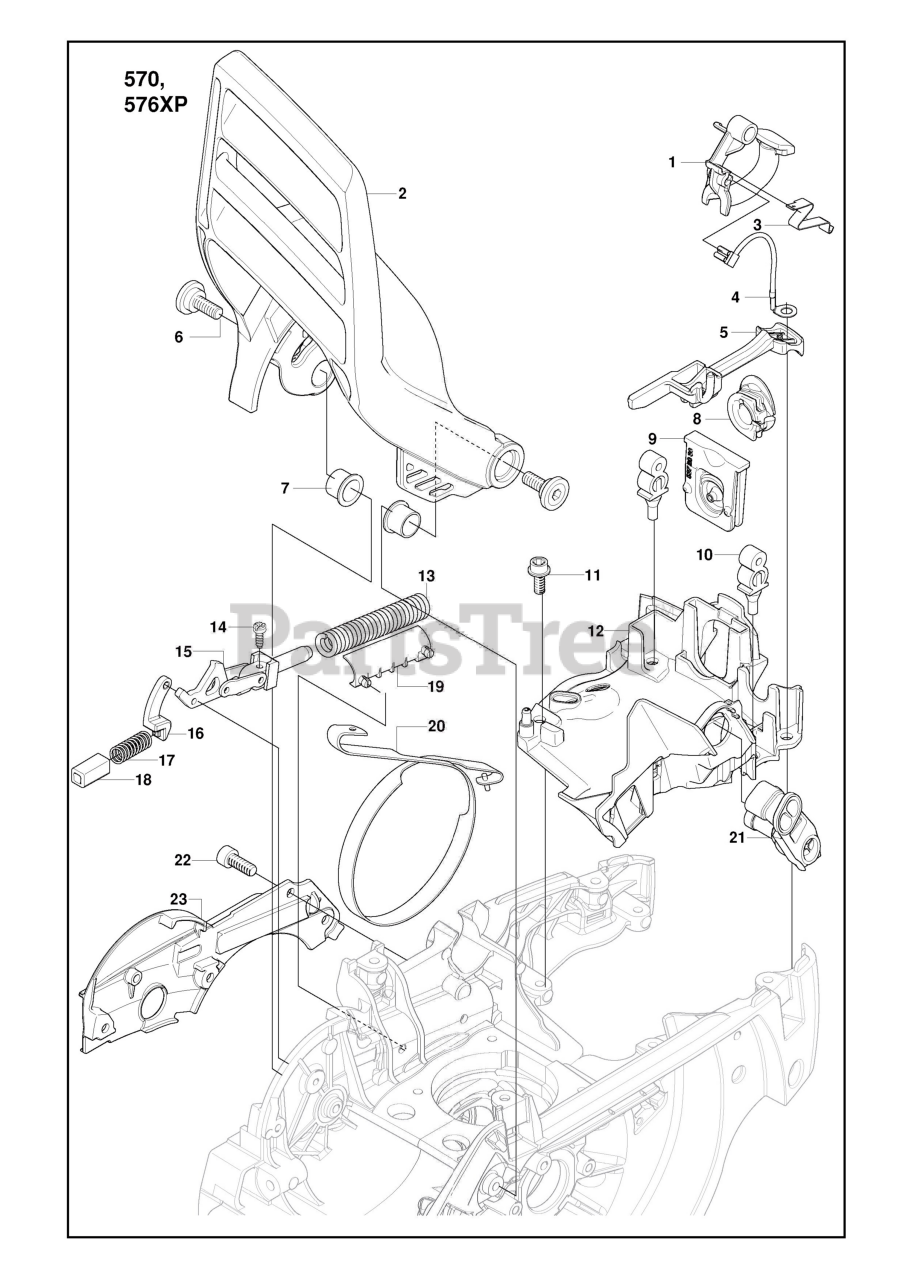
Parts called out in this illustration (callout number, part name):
2	CHAIN BRAKE
5	CHOKE CONTROL
13	BRAKE SPRING
15	KNEE JOINT
17	LOCK SPRING
19	%SUPPORT
20	BRAKE BAND
